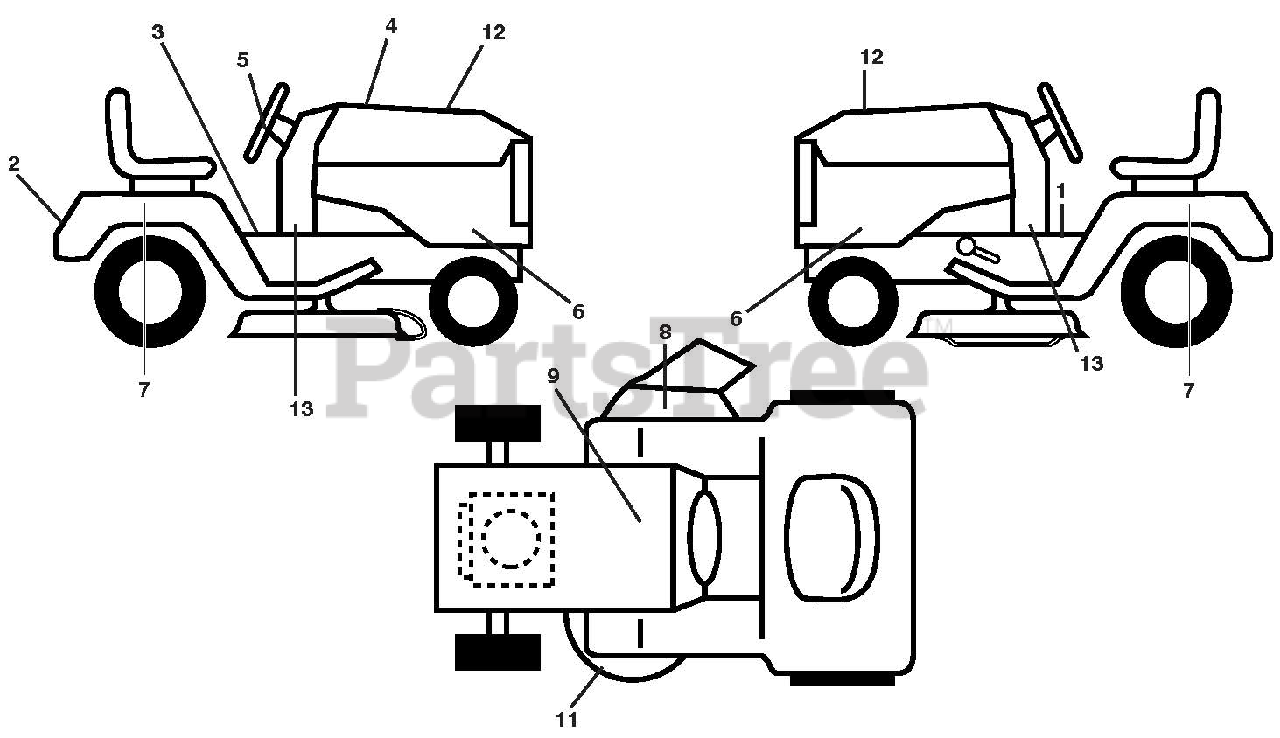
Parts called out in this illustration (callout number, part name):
1	DECAL, FENDER WARNING
2	DECAL.FENDER.REAR.ARIENS
3	DECAL.FENDER
4	DECAL, REPLACEMENT
5	DECAL.WHEEL.STEER.ARIENS
6	DECAL.SDPNL.PWRDBY KOHL.ARIENS
7	DECAL, FENDER
8	DECAL DECK/DEFLECT. WARNING
9	DECAL.BAT.DAN/POI P/L SYM.WPN
11	DECAL.V-BELT.SCH.
12	DECAL.HOOD.LH/RH.
13	DECAL, LWDSH
